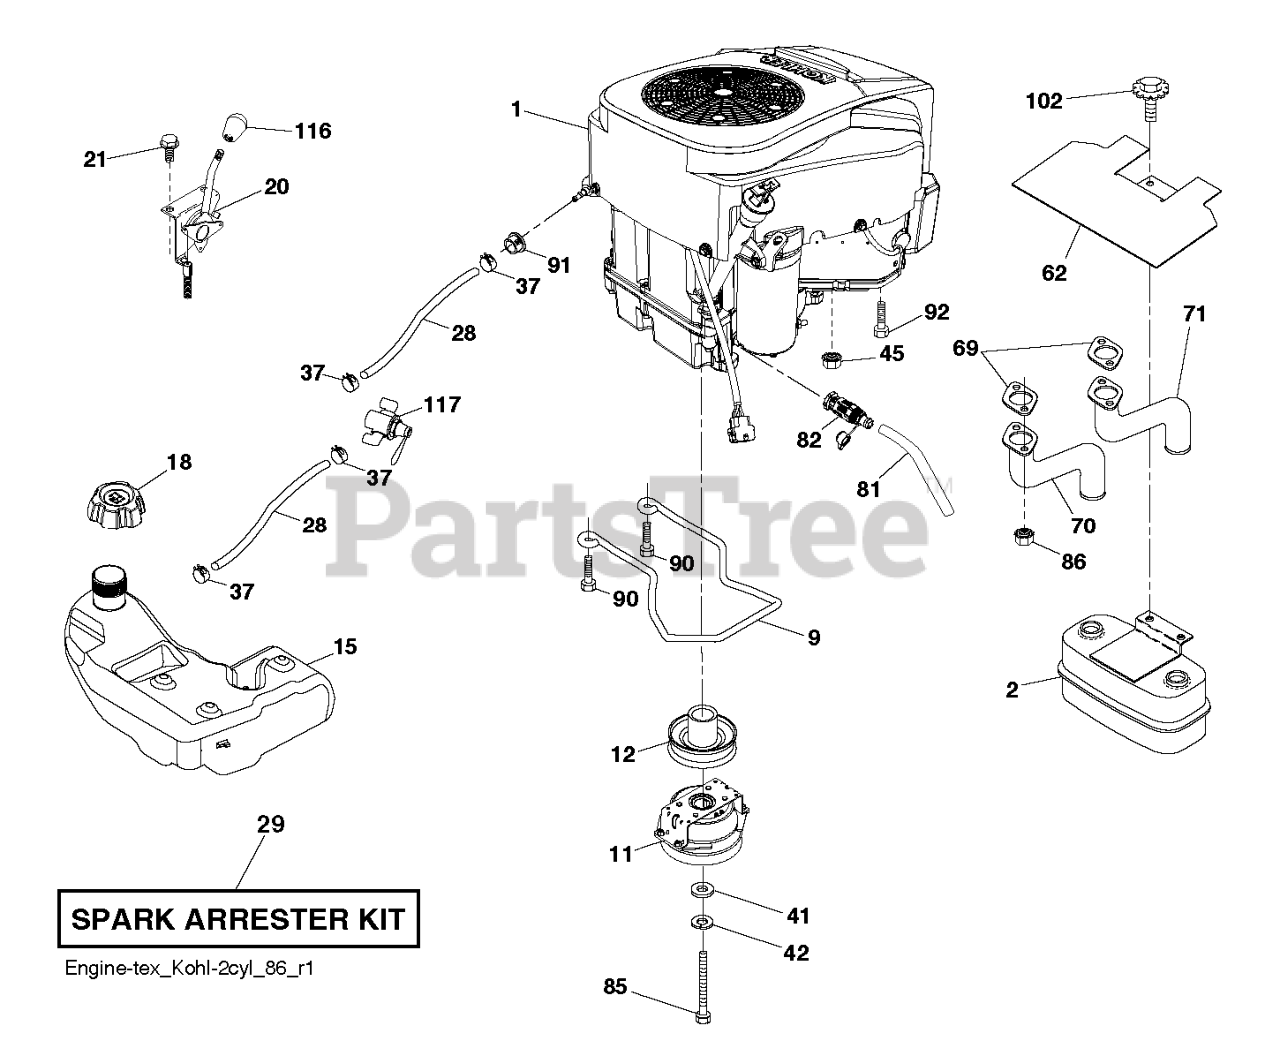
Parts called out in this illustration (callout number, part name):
2	MUFFLER.ASM.TWIN.MNTG.BRACKET
11	CLUTCH. 5.0 PD. 2.5 OFFSET
12	PULLEY.EXTENDED.SHAFT.GROUND
15	Tanks
18	CAP ASSY FUEL 3" GRAY
20	CONTROL.THROTTLE.PRO.
28	LINE.FUEL.64"REAR.EMIS
29	KIT.SPARK ARRESTOR 794945 B&S
37	HOSE CLAMP
62	SHIELD.HEAT.MUFFLER
70	TUBE.EXHAUST.LH.FR961/FR730
71	TUBE.EXHAUST.RH.FR961/FR730
81	TUBE, DRAIN OIL ASM.
82	VALUE.OIL.DRAIN
85	BOLT.HEX.7/16-20X3.GR5.YELLOW
86	NUT.HEX.FLANGE.TOPLOCK
90	SCREW 3/8-16X1
91	BUSHING.1.375OD
92	SCREW 3/8-16X1
102	SCREW
116	KNOB - SHIFT
117	VALVE FUEL RESERVE
